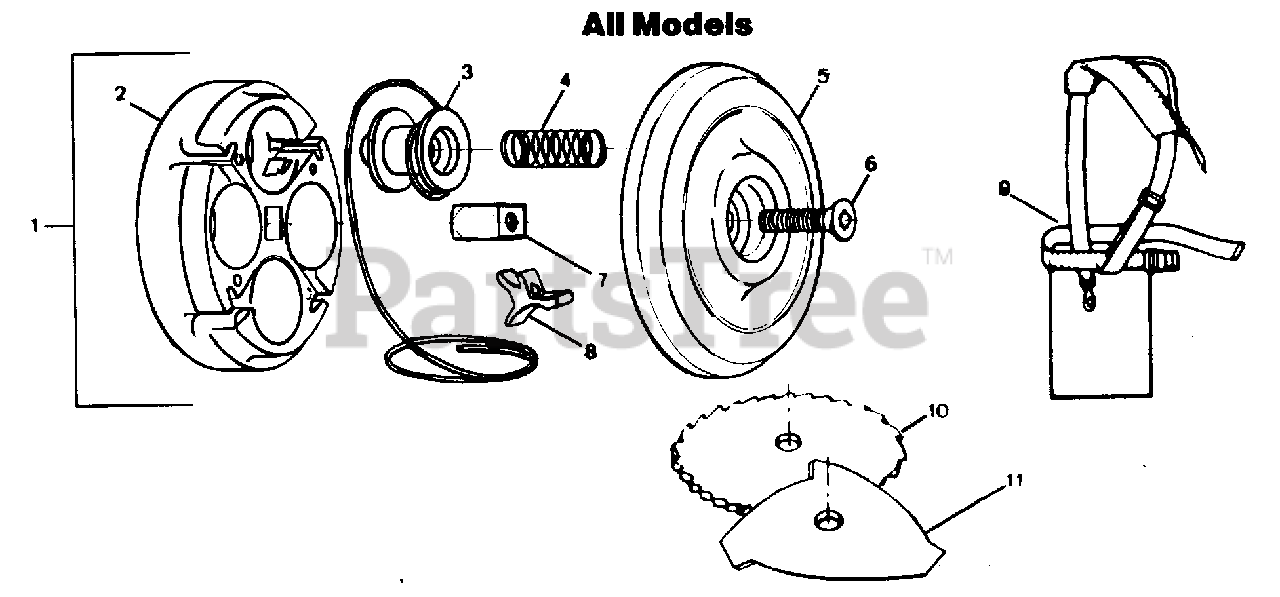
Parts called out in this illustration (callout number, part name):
1	Head Assembly
3	Spool w/Line
4	Spring, Spool Retainer
5	Lower Cover
6	Socket Head Cap Screw 3/8 NC x 1-1/4
7	Arbor Post
8	Retainer, Line
9	Shoulder Strap
10	10" Brush Blade (Optional)
11	TriKut Weed Blade (Optional)
11	8" -Model 670
11	11" -Models 650,657
